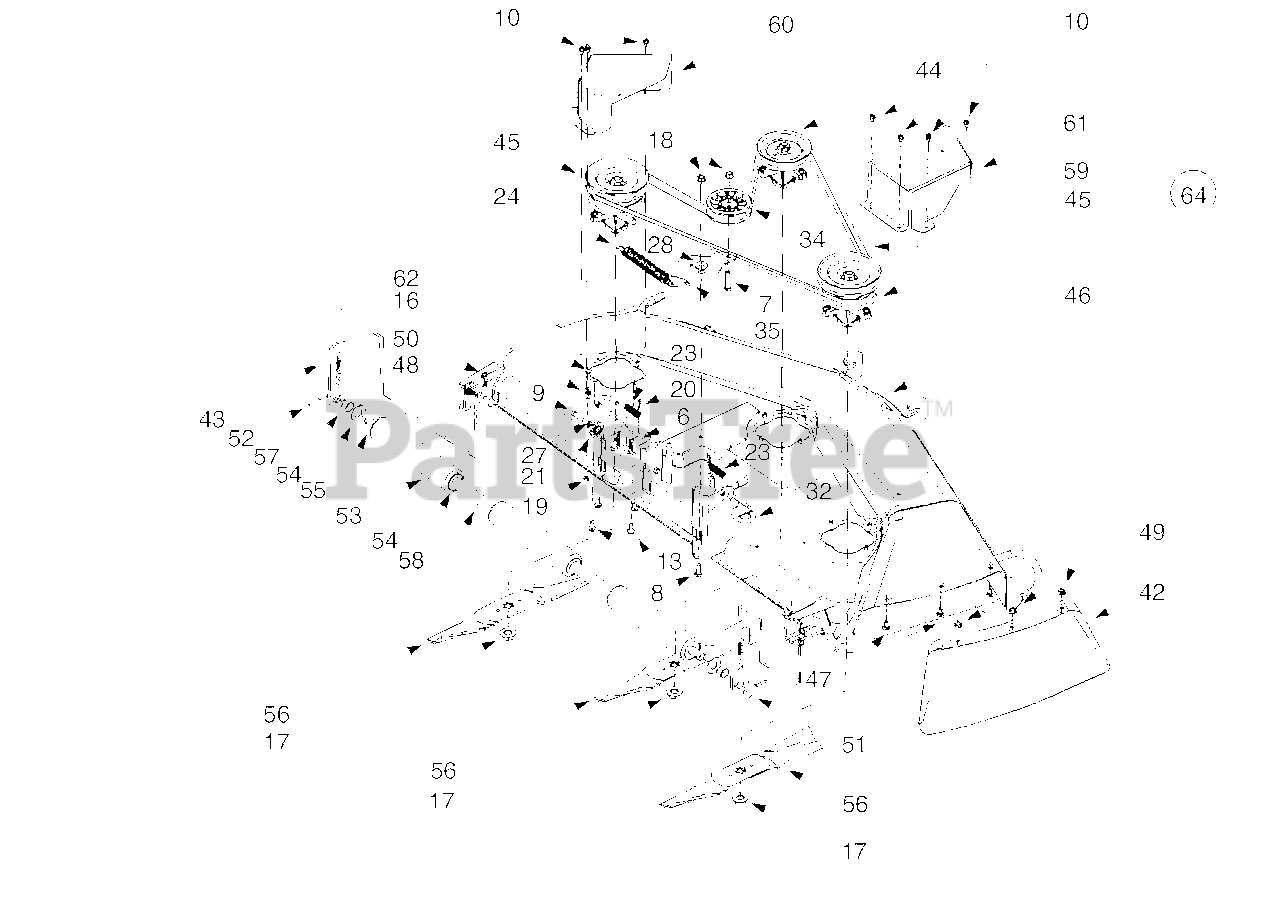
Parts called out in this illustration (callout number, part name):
6	Carriage Screw, 1/4-20 x .5
7	Hex Cap Screw, 3/8-16 x 1.75
8	Hex Cap Screw, 3/8-16 x 1.0
9	Hex Cap Screw, 5/16-18 x 1.25
10	Self Tapping Screw,1/4-20 x .5
13	Self Tapping Screw, 5/16-18 x .75
16	Center Lock Nut, 1/4-20
17	Hex Flange Nut, 5/8-18
18	Flange Lock Nut, 3/8-16
19	Hex Flange Lock Nut, 1/4-20
20	Internal Cotter Pin, .072 x 1.12
21	Deck Adjustment Gear
23	Compression Spring, .406 x .531 x 1.75
24	Extension Spring, .91 x 7.33
27	Lock Washer, 5/16
28	Shoulder Spacer, .625 x .169
32	Deck Release Pin
34	Flat Idler Pulley, 3.5 OD
44	Center Spindle Assembly, 5 Dia.
45	Double Pulley Spindle Assembly
48	Clevis Pin, .50 Dia. x .78
49	Hex Flange Lock Nut, 5/16-18
50	Click Pin, .092 x 1.64
51	Spring Pin, 1/4 Dia. x 1
52	Spring Pin, 3/16 x 1.25
53	Deck Roller
54	Flat Washer, .78 x 1.59 x .06
55	Deck Roller Shaft, .75 Dia. x 47.12
56	Blade, Star Center, 17.3
57	Spacer, .752 x 1.0 x .53
